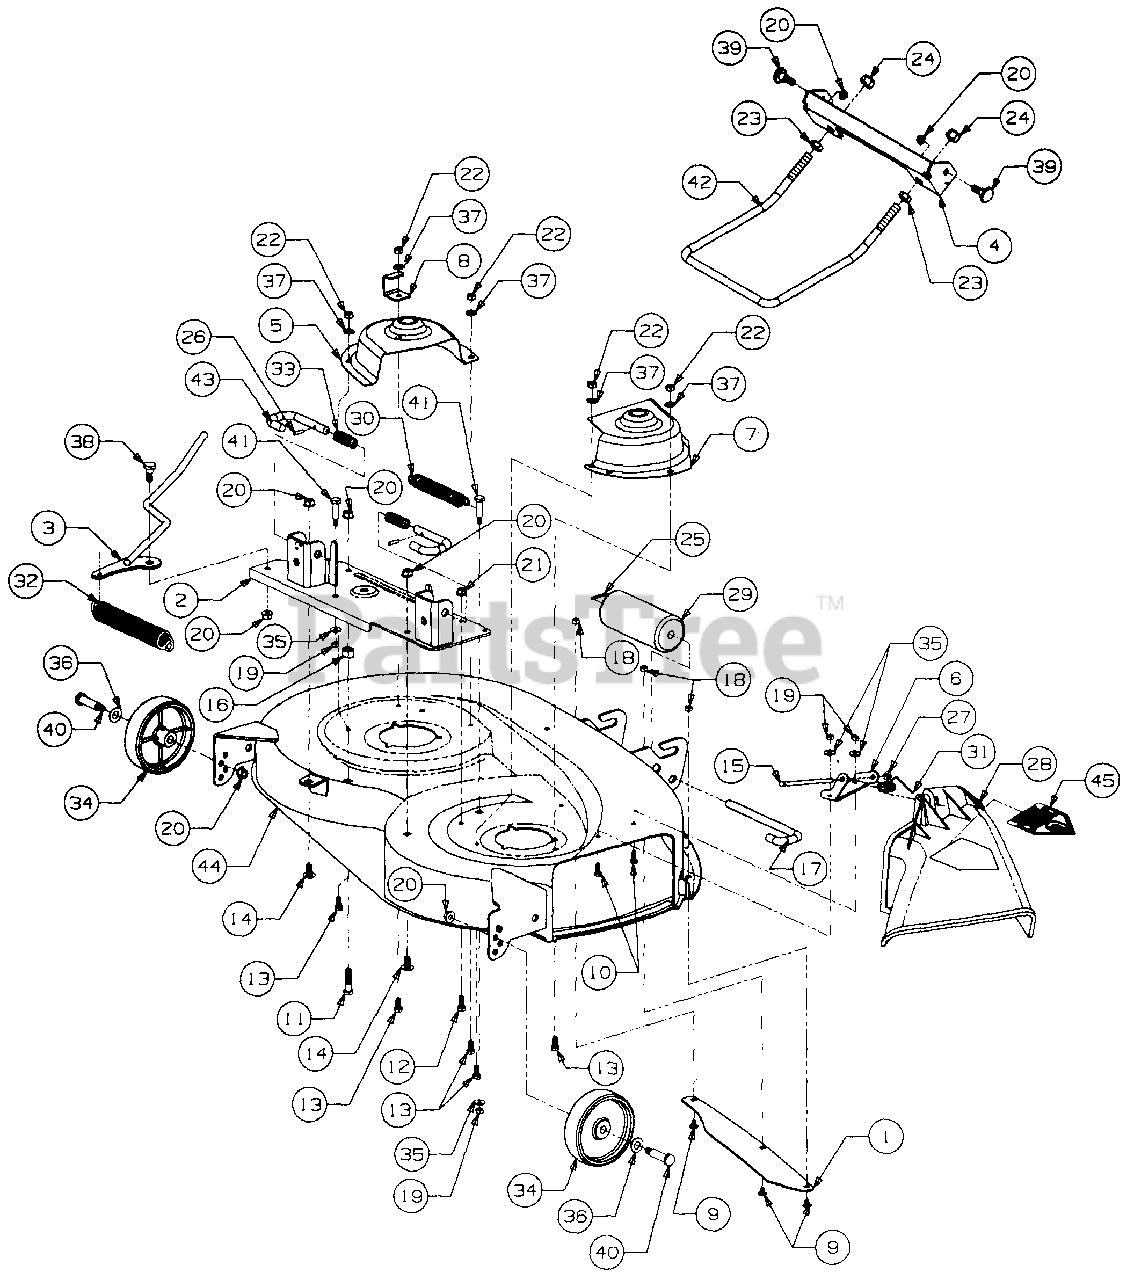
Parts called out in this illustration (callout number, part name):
5	Cover, LH Belt
6	Bracket, Hinge Mtg
9	Bolt, Carriage, 1/4-20 x .50 Lg
10	Screw, Hex Cap, 1/4-20 x 2.62 Lg GR2
11	Screw, Hex Cap, 3/8-16 x 1.50 Lg GR5
12	Screw, Hex Cap, 5/16-18 x .75 Lg GR5
13	Screw, Hex Cutting, 5/16-18 x .62 Lg
14	Bolt, Sht Nk Carriage, 3/8-16 x .75 Lg GR5
15	Pin, Hinge, .25 Dia x 6.75 Lg
16	Spacer, .395 ID x .75 OD x .440 Lg
17	Pin, Roller, 1/2 Dia x 7.31 Lg
18	Nut, Hex Sems, 1/4-20
19	Nut, Hex, 1/4-20
20	Nut, Hex Flanged Lock, 3/8-16
21	Nut, Hex Flange Top Lock 5/16-18
22	Nut, Hex, 5/16-18 GR5
23	Nut, Hex Jam, 1/2-13 GR5
24	Nut, Hex Top Nylon Lock, 112-13
25	Pin, Cotter, 1/8 Dia x 1.0 Lg
26	Pin, Spirol Spring, 3/16 Dia x .75 Lg
27	Cap, Speed Nut
28	Deflector Assy, Chute
30	Spring, Extension, .88 OD x 6.12
31	Spring, Torsion
32	Spring, Extension, 1.25 OD x 8.15 Lg
33	Spring, Compression
34	Wheel, Deck, 5 in. Dia
35	Washer, Bell, .265 x .75 x .062 Thk
36	Washer, Flat, .51 0 x 1.0 x .060 Thk
37	Washer, Flat, .34 x .68 x .062 Thk
38	Bolt, Shoulder, .498 Dia x .340 Lg
39	Bolt, Shoulder, .50 Dia x .434 Lg
40	Bolt, Shoulder, .498 Dia x 1.64 Lg
41	Bolt, Shoulder, .375 Dia x 1.16 Lg
42	Rod, Front Lift
43	Pin, Mower Support
44	Deck Assy w/Graphics
45	Graphic, Danger
